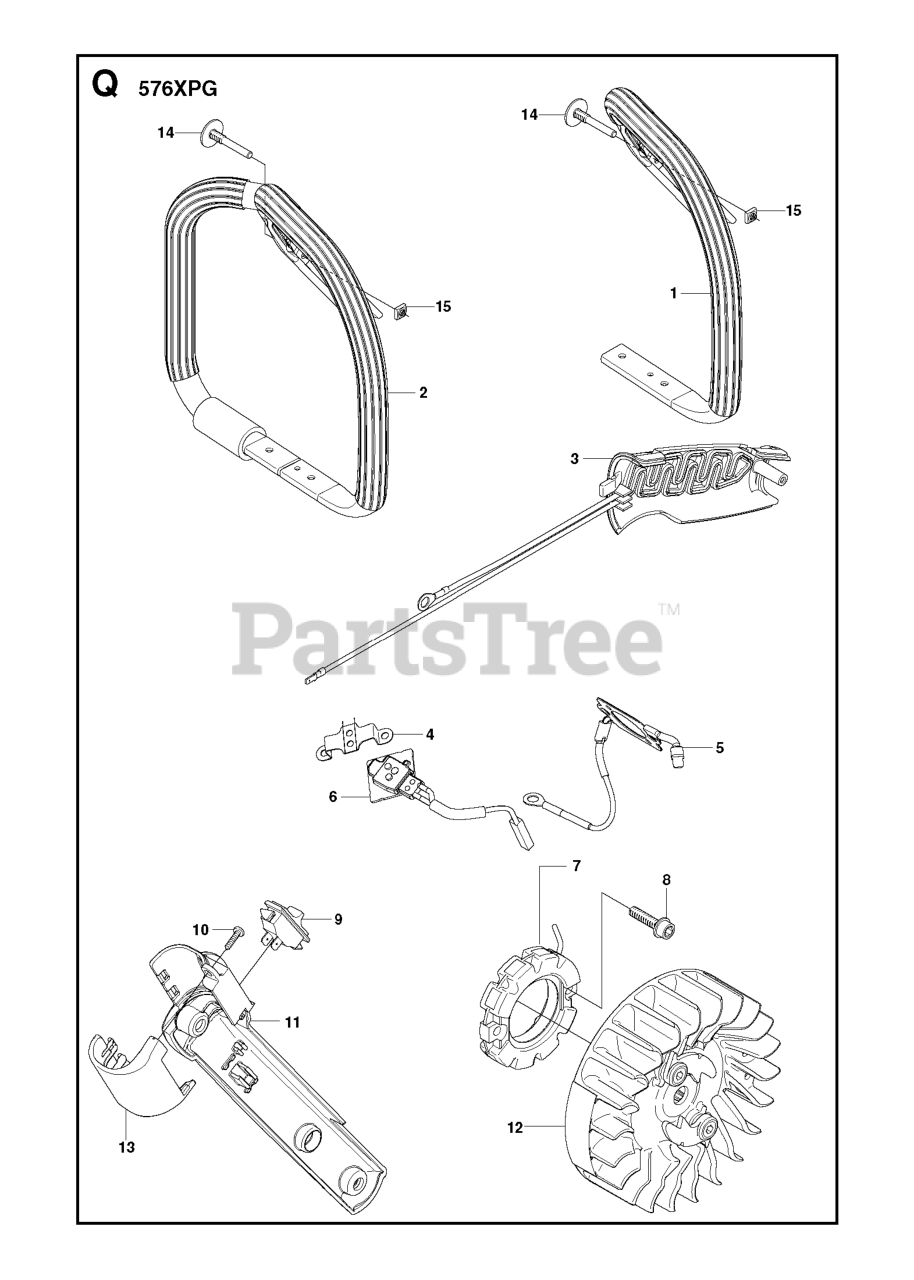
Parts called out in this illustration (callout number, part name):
1	HANDLE (G)
2	HANDLE (WAG)
5	HANDLE CIRCUIT
6	THERMOSTAT
